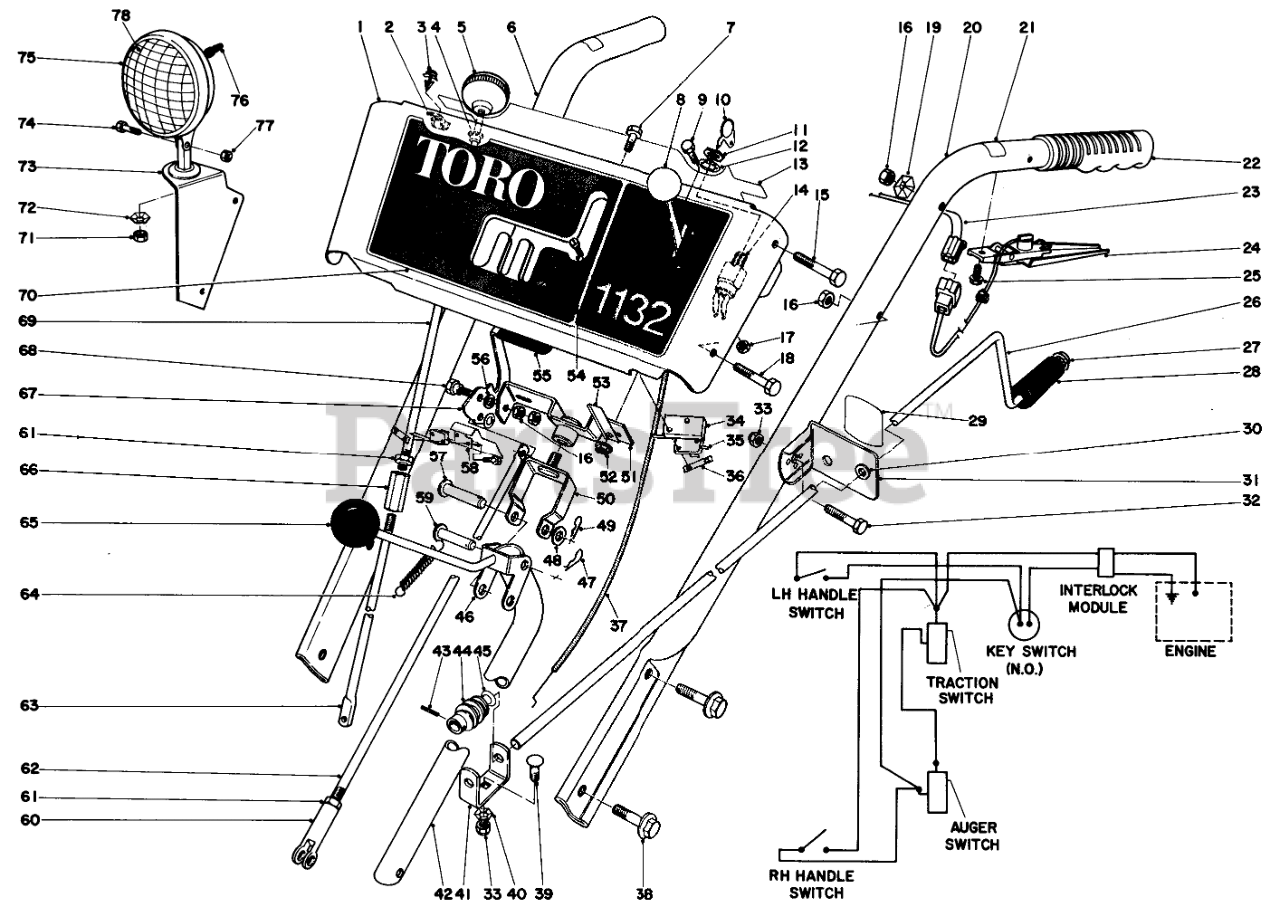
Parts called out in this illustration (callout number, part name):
1	Escutcheon Plate (Incl. Ref. #13&70)
2	WIRE CLAMP
3	Mounting Stud
4	NYLINER #6LI-FF TYPE 7
5	KNOB-LEVER
6	Handle Right
7	SCREW-HH
8	CONTROL KNOB
9	HEX HEAD SEMS 10-24X1/2
10	Key
11	NUT-HH
12	SCREW-SET
13	Decal-Escutcheon Back
14	Key Switch (Incl. Ref. #11 & 12)
15	SCREW-HH
16	NUT-LOCK, CONE
17	Nut
18	SCREW-HH
19	Washer
20	HANDLE LEFT
21	INTERLOCK DECAL
22	Grip Handle
23	WIRE HARNESS INTERLOC
24	INTERLOCK HDLE SWITCH
25	SCREW
26	Chute Control Rod
27	RETAINER-PUSH ON
28	GRIP-CONTROL, CHUTE
29	CHUTE DECAL
30	Bushing
31	Bracket-Chute Control Mtg. (Incl. Ref. #29 & 30)
32	SCREW-HH
33	NUT-LOCK, NI
34	SWITCH MTG PAD
35	SWITCH-MICRO
36	NUT-SPEED
37	Throttle Contrl
38	SCREW-HHF
39	BOLT-CARR
40	WASHER-LOCK
41	WORM BRACKET
42	Rod Traction Shift
43	PIN-SPRING
44	GEAR-WORM, CHUTE
45	WASHER-SPRING
46	SHIFT ROD WA
47	PIN-COTTER
48	WASHER-FLAT
49	PIN-HAIR
50	PIVOT BRKT WA
51	SWIVEL BLOCK WA
52	NUT-LOCK, HHF
53	Retainer Wire
54	SCREW-SPH
55	AUGER CLUTCH HND GRIP
56	WASHER-PLAIN
57	PIN-CLEVIS
58	SWITCH BRKT
59	PIN-CLEVIS
60	CLEVIS
61	NUT-HJ
62	DRAG LINK
63	LOWER WHL CLUTCH ROD
64	CONT ROD SPRING 0
66	WHL ROD COUPLING
67	Auger Clutch Handle
68	SCREW-SHOULDER
69	UP WHEEL CLUTCH ROD
70	Decal-Escutcheon
71	NUT-HEX
72	LOCKWASHER-PYRAMID
73	Lamp Mount
74	SCREW-HH
75	HEADLAMP ASM
76	BOOT-SWITCH
78	SEAL BEAM BULB 60W 12
